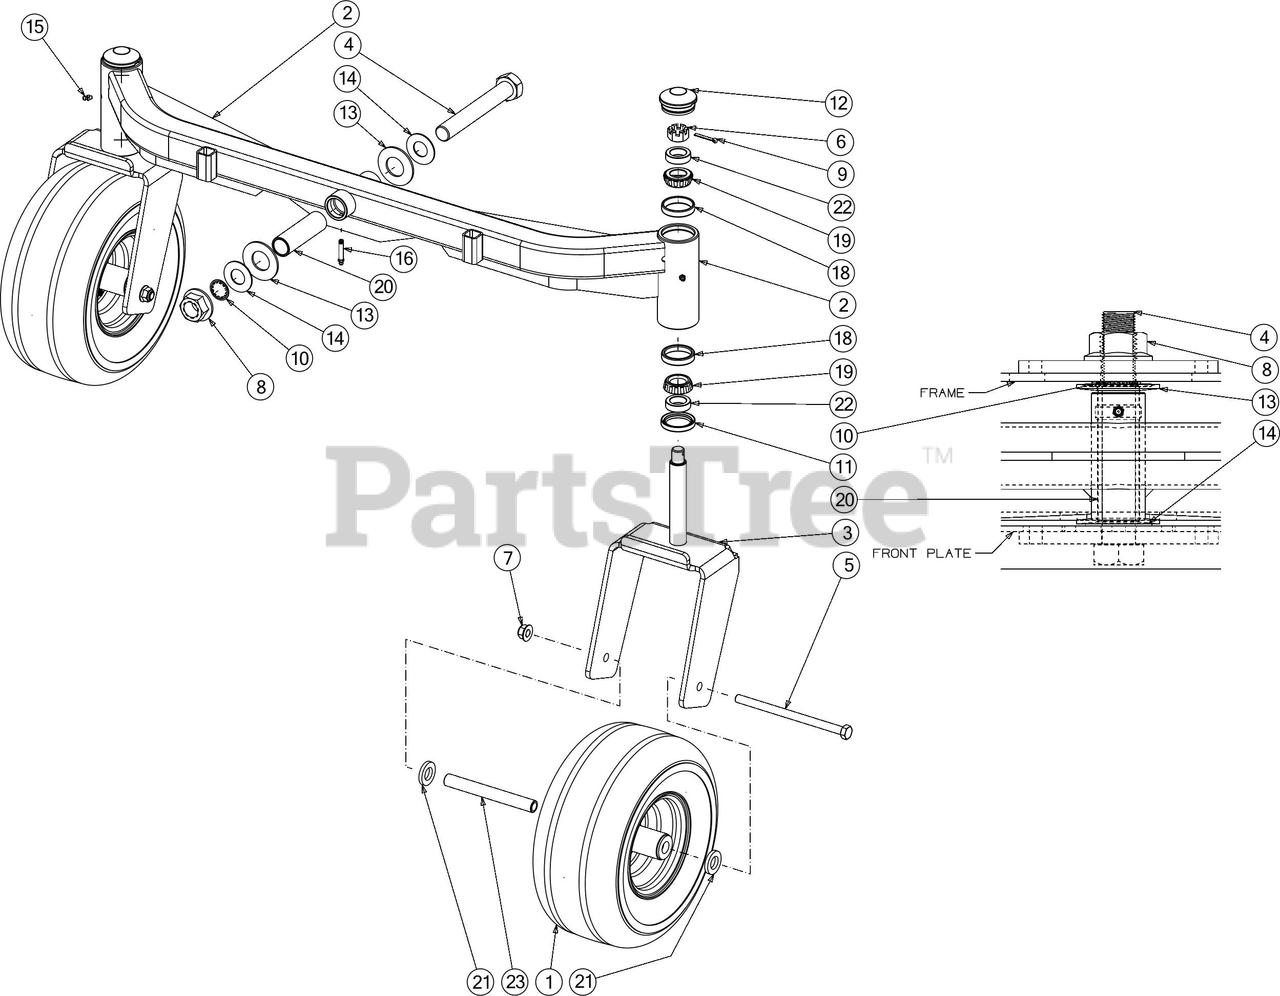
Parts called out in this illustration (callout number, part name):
1	WHEEL ASSEMBLY (13 x 6.50-6) (BEIGE)
4	SCREW 1-14 x 7.0 GR5
5	SCREW 1/2-13 x 7.50 GR5
6	HEX NUT CASTLE 3/4-16
8	HEX FLANGE NUT
9	COTTER PIN-5/32 DIA
10	RETAINING RING
12	AXLE GREASE CAP
13	BELL WASHER 1.25ID x 2.5 x .180
14	FLAT WASHER 1.0 x 2.0 x .075
15	GREASE ZERT 1/4-28
16	GREASE FITTING
18	BEARING CUP
19	BEARING CONE
21	SPACER .812 ID x .218 LG
